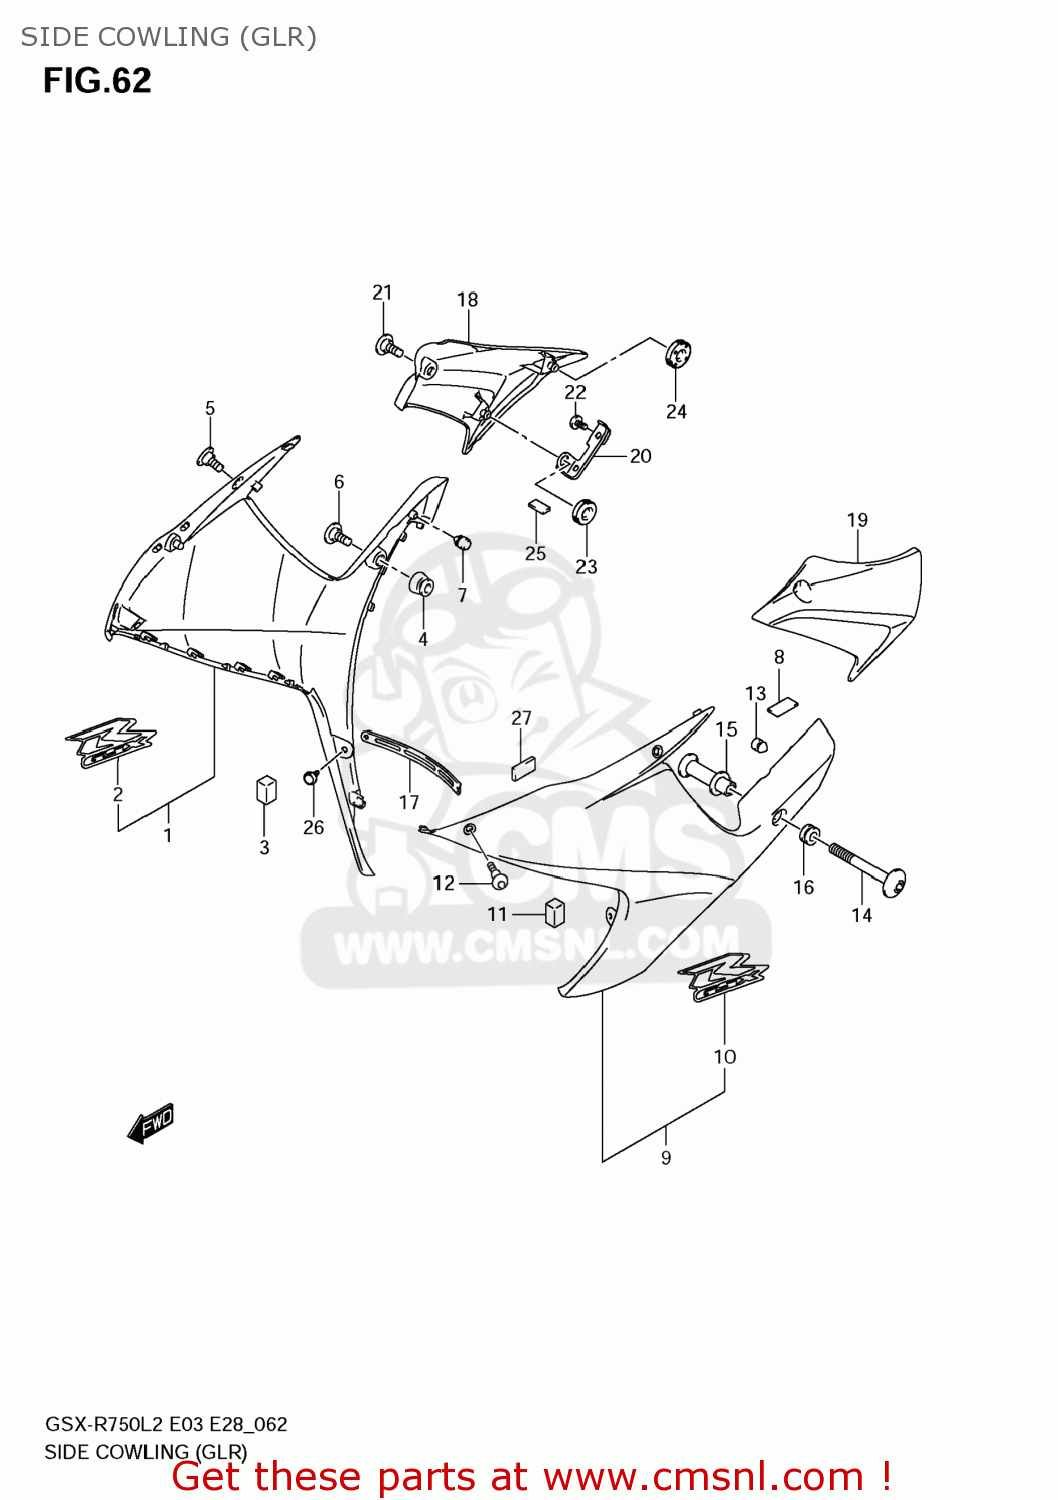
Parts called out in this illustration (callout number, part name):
1	COWLING,SIDE,R(WHITE)
2	EMBLEM,GSXR,R
3	CUSHION,SIDE COWL FR
4	CUSHION,UNDER COWLING,L
5	SCREW(5X13)
6	BOLT(6X20)
7	CUSHION
8	CUSHION,FUEL TANK NO.2
9	COWLING,SIDE,L(WHITE)
10	EMBLEM,GSXR,L
11	CUSHION,SIDE C
12	SCREW(5X13)
13	CUSHION
14	SCREW,SIDE COWL,L
15	SPACER,SIDE COWL,L
16	CUSHION
17	PLATE,UNDER COWL CTR
18	COVER,SIDE COWLING,R
19	COVER,SIDE COWLING,L
20	BRACKET,COVER SIDE,R
21	SCREW(5X13)
22	SCREW(6X12)
23	CUSHION
24	CUSHION
25	CUSHION
26	CLIP
27	PROTECTOR(30X80X1)
